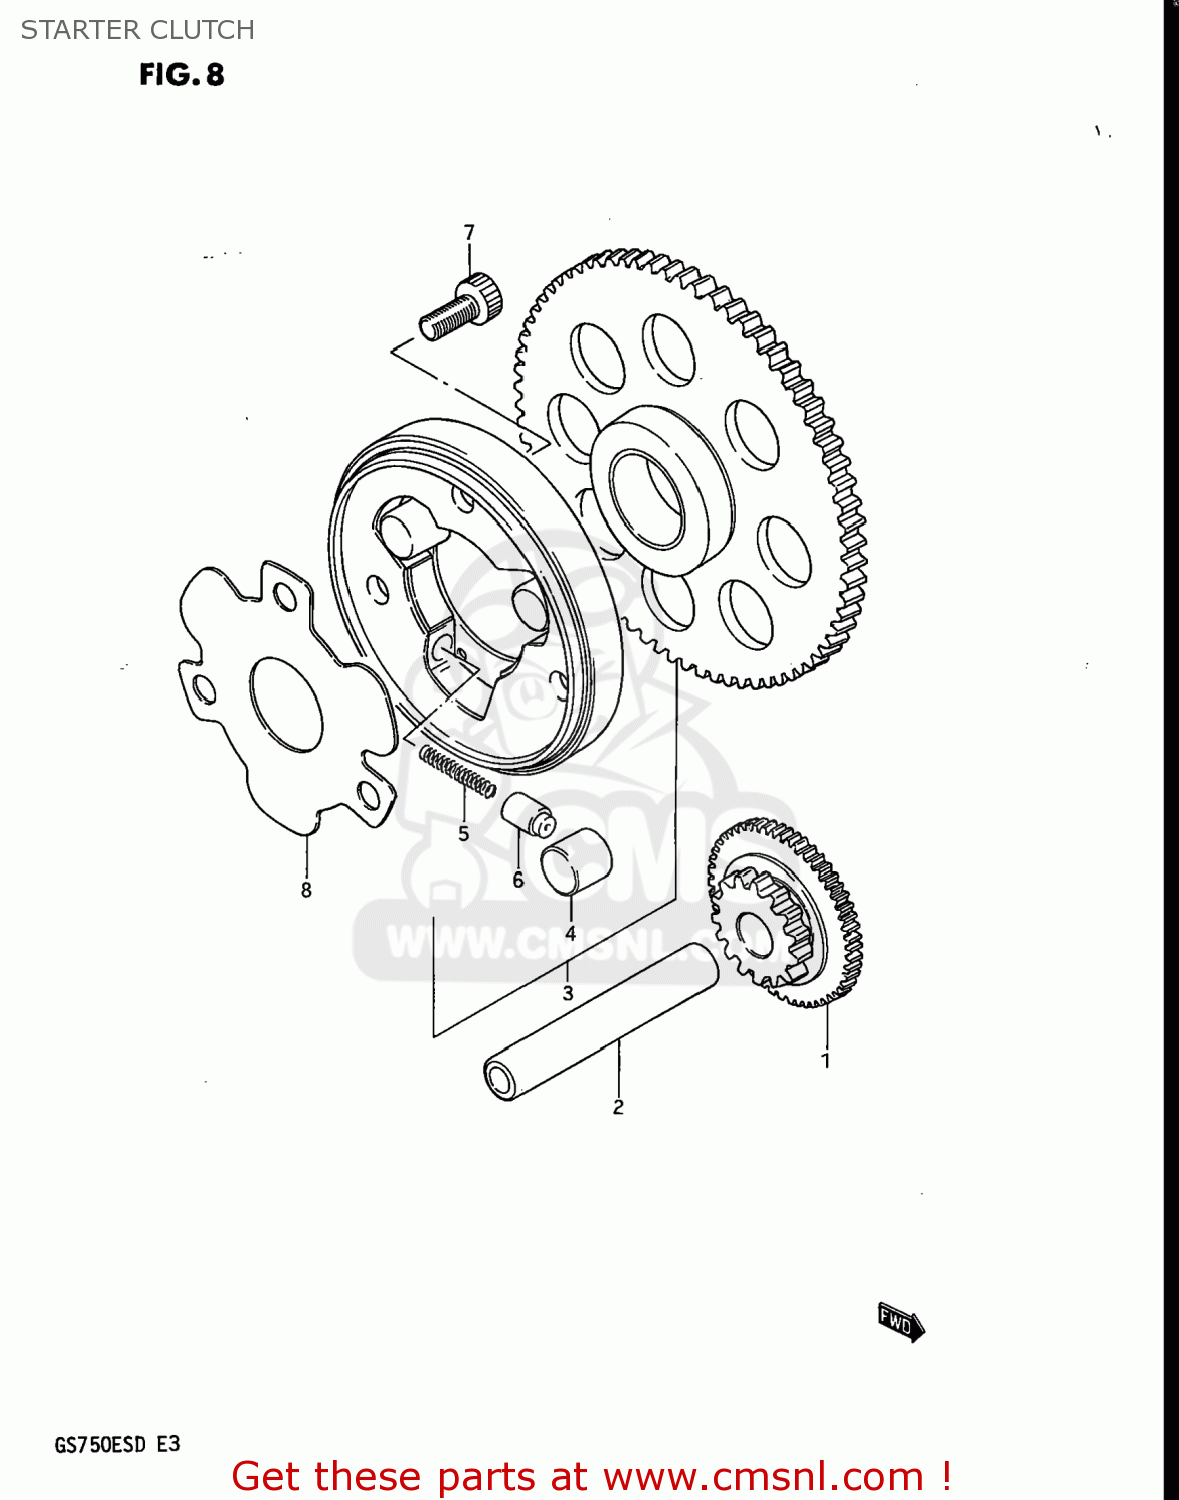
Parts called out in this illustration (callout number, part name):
1	GEAR,STARTER IDLE
2	PIN(7.4X13X56)
3	CLUTCH SET,STARTER
4	PIN(14X13)
5	SPRING
6	PIECE,PUSH
7	BOLT
8	SHIM,STARTER CLUTCH HUB
